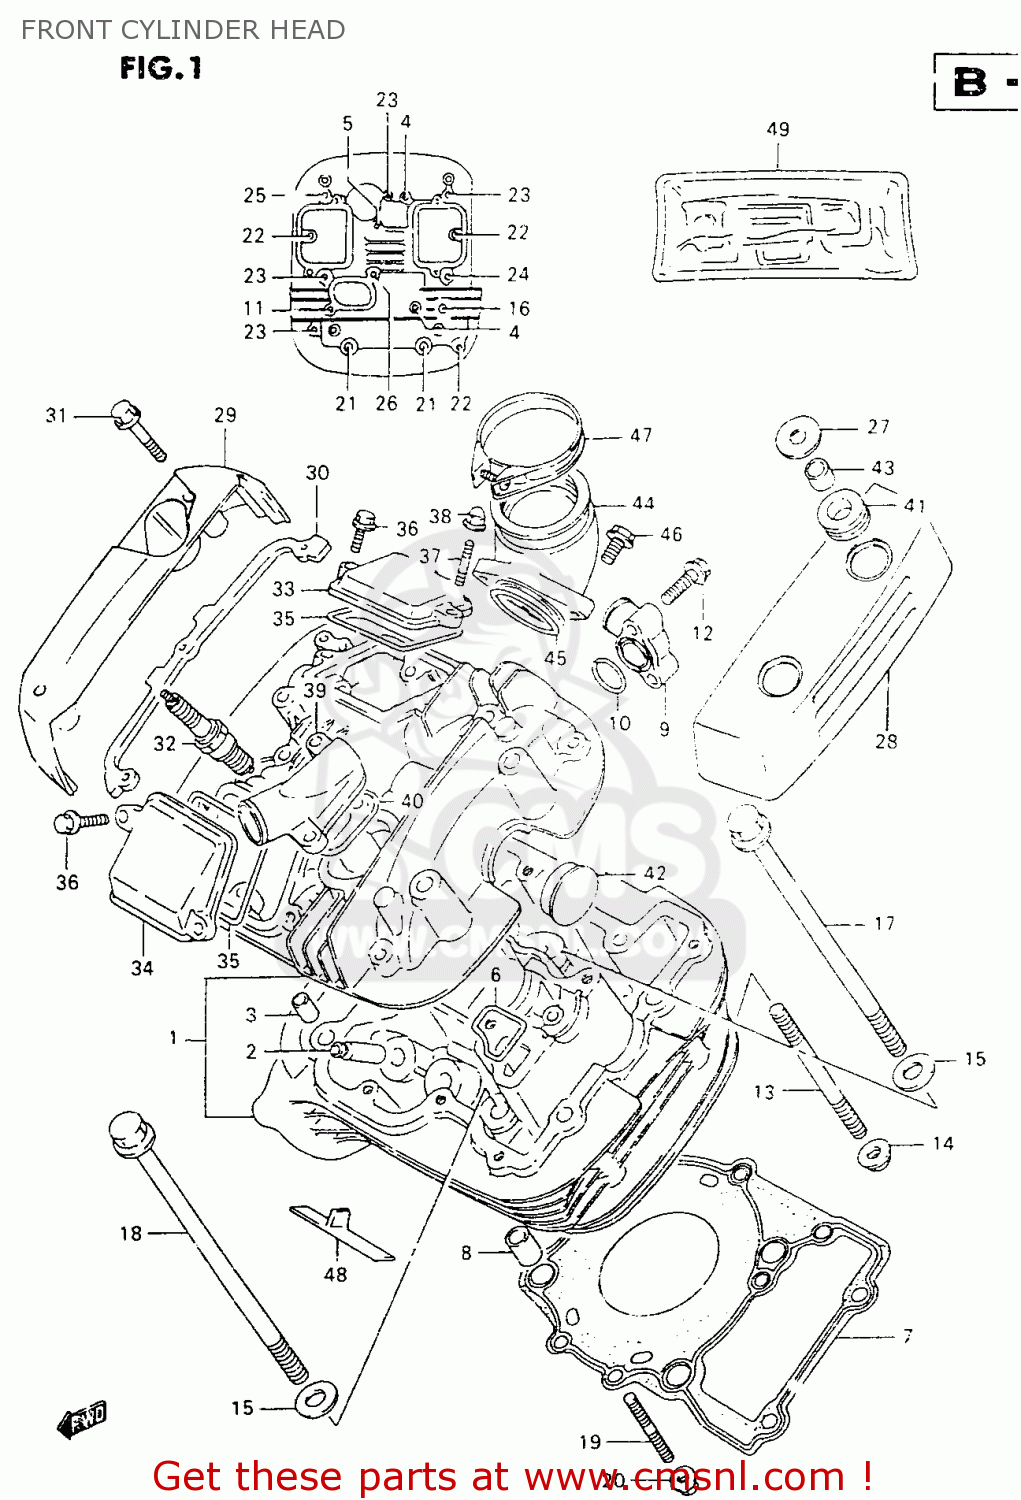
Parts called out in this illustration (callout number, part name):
1	HEAD ASSY,CYLINDER FR
2	GUIDE,VALVE
3	PIN(8.4X11X14)
4	BOLT(6X50)
5	BOLT(6X55)
6	GASKET,CYLINDER HEAD WATER (NAS)
7	GASKET,CYLINDER HEAD FR (NAS)
8	PIN
9	UNION,CYLINDER HEAD WATER
10	O RING(D:2.4,ID:17.8)
11	BOLT
12	SCREW
13	BOLT,STUD
14	NUT
15	WASHER (10.5X22X2.3)
16	BOLT(8X140)
17	BOLT(10X155)
18	BOLT(10X165)
19	STUD BOLT
20	NUT
21	BOLT(8X245)
22	BOLT
23	BOLT
24	BOLT
25	BOLT
26	BOLT(6X55)
27	WASHER(8.5X24X1.6)
28	CAP,CYL HEAD COVER,FL & RR
29	CAP,CYLINDER HEAD COVER,F-R
30	CUSHION,FR,R CAP
31	BOLT(6X40)
32	PLUG,SPARK(DPR8EA-9)
33	CAP,INSPECTION INTAKE
34	CAP,INSPECTION EXHAUST
35	GASKET,INSPECTION CAP (NAS)
36	BOLT
37	STUD 6X16
38	NUT
39	UNION,WATER OUTLET
40	GASKET,WATER OUTLET UNION (NAS)
41	CUSHION
42	PLUG(OD:30)
43	BUSH
44	PIPE,INTAKE,FRONT
45	O-RING (D:2.4 ID:39.7)
46	BOLT
47	CLAMP
48	PLATE,HEAD COVER RR
49	GASKET SET (NAS)
